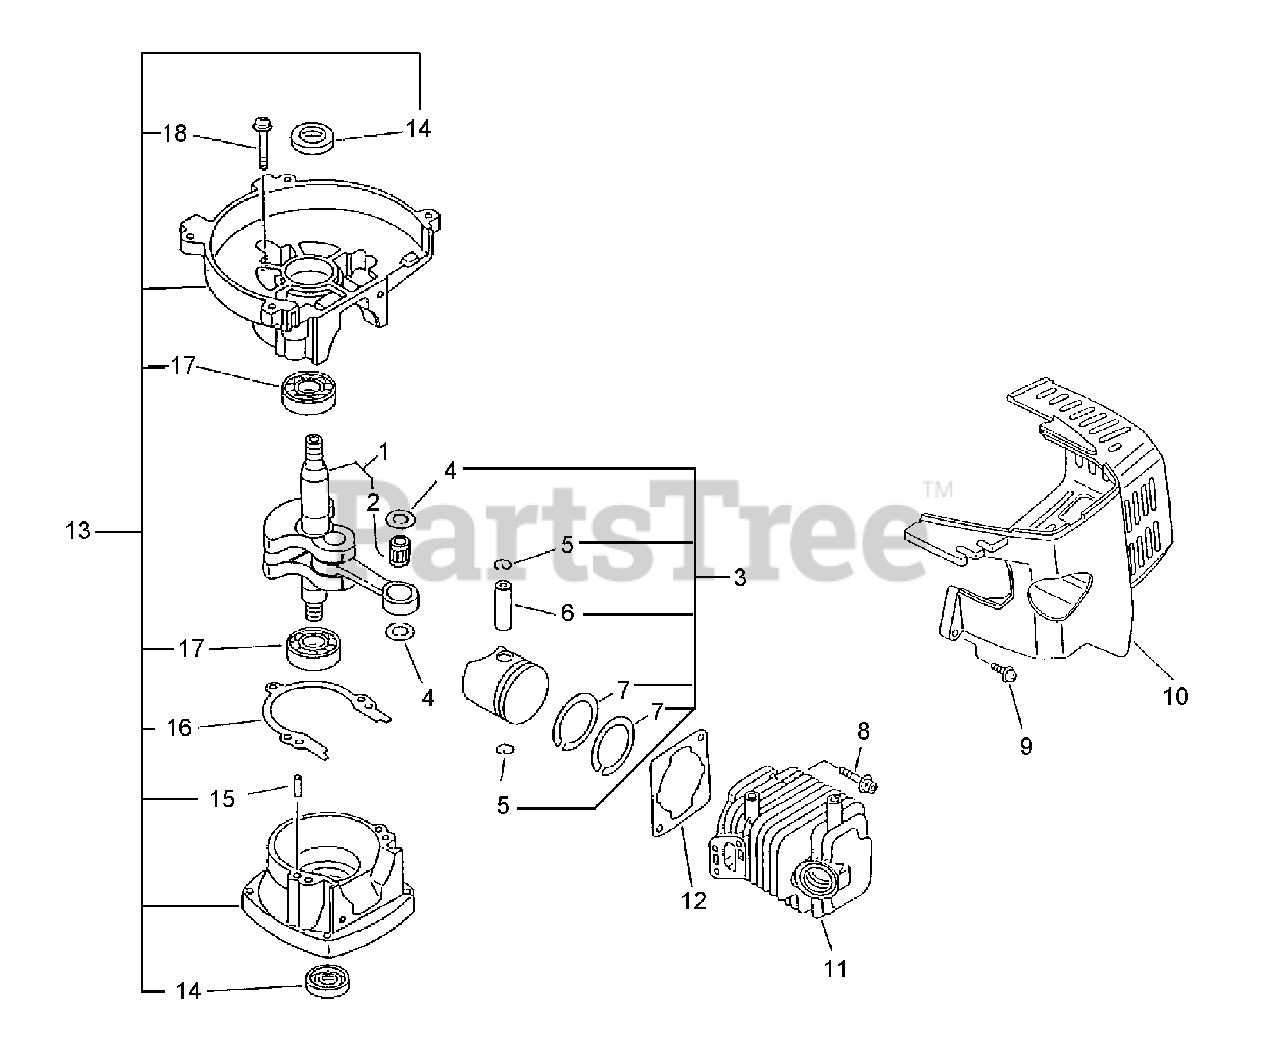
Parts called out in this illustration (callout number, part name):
1	CRANKSHAFT ASSY
2	BEARING, NEEDLE
2	BEARING, NEEDLE - 8
3	PISTON KIT
4	SPACER, PISTON
4	WASHER
5	RING, RETAINING
6	PIN, PISTON
7	RING, PISTON
8	SCREW - 5X22
9	SCREW - 4X22
10	COVER, ENGINE
11	CYLINDER
12	GASKET, CYLINDER
13	CRANKCASE SET
14	SEAL, OIL
15	PIN - LOCATING
16	GASKET, CRANKCASE
17	BEARING, BALL - 6201
18	SCREW - 5X28
